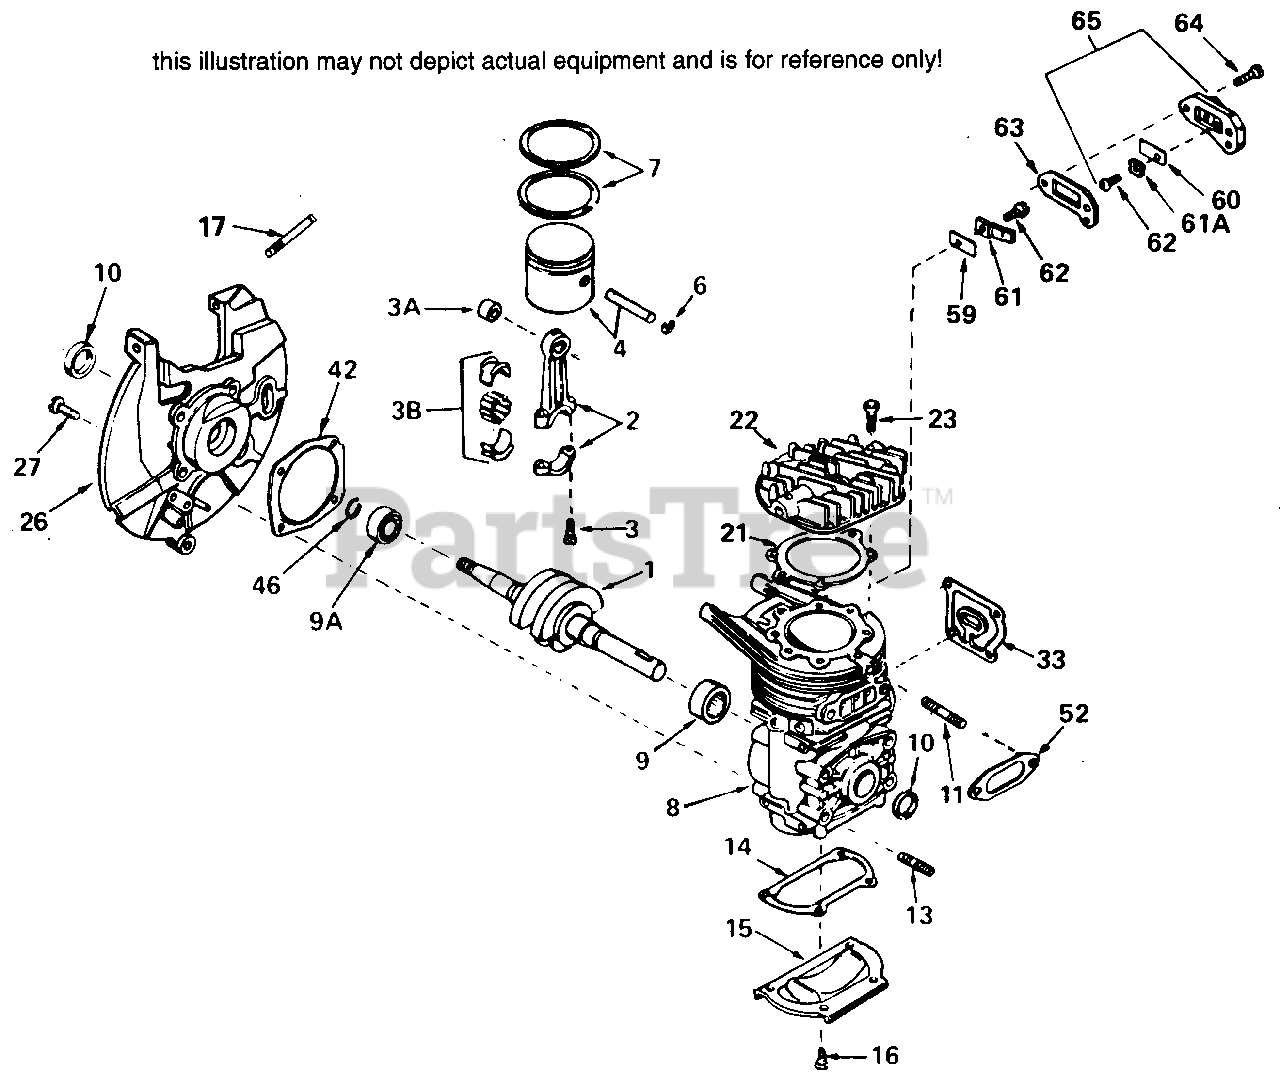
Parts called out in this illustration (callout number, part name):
1	"Crankshaft
2	Rod Assy., Connecting Incl. 3, 3A &3B
3	Screw, Connecting rod
3A	Bearing, Cartridge
3B	Bearing & Liner Set, Needle
4	Piston & Pin Assy. (Incl. 6)
6	Ring, Piston pin retaining
7	Ring Set, Piston
8	Cylinder Order SB if replacement isre q.
9	Bearing, Cartridge
9A	Bearing, Ball
10	Seal, Crankshaft
11	Stud, Exhaust
13	Stud, Mounting
14	Gasket, Cover
15	Plate, Cover
16	Screw, Torx T-25, 10-24 x 1/2"
17	Shaft, Air vane
21	Gasket, Cylinder head
22	CYL HEAD
23	Screw, Torx T-30, 1/4-20 x 3/4"
26	Blower housing Base (Incl. 10 & 17)
27	Screw, Torx T-30, 1/4-20 x 5/8"
33	Gasket, Port
42	Gasket, Blower housing base
46	Ring, Retaining Used on early product ion
52	Gasket, Exhaust
59	Reed, Compression release
60	Reed, Compression release
61	Plate, Reed hold-down
61A	Plate, Reed hold-down
62	Screw, 6-32 x 3/8"
63	Gasket, Compression release
64	Screw, 10-24 x 5/8"
65	Comp. Release Cover Assy. (Incl. 60,6 1A & 62)
